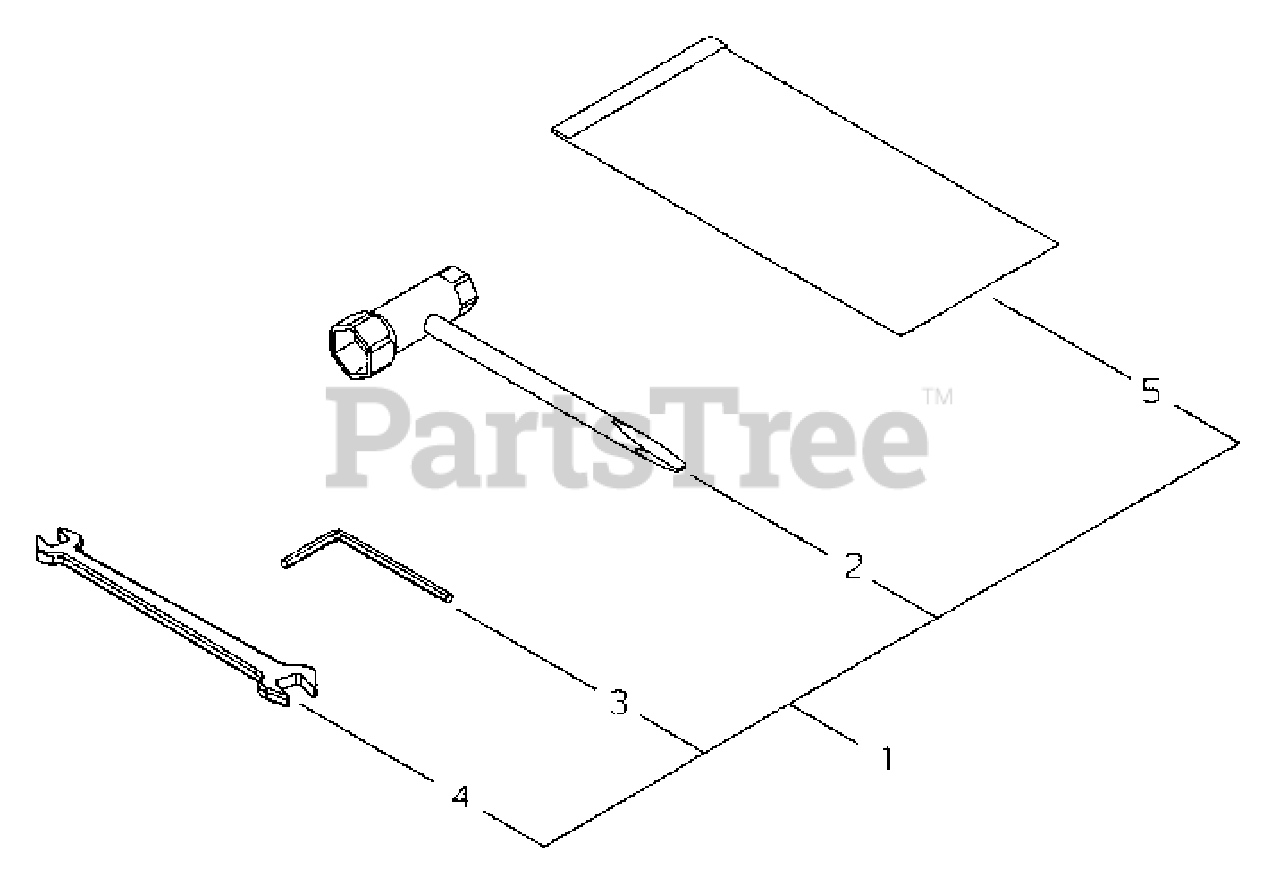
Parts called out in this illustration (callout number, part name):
1	TOOL KIT
2	T-WRENCH - 13X19mm
3	HEX KEY - 4mm
4	SPANNER - 8X10mm
5	BAG, TOOL
